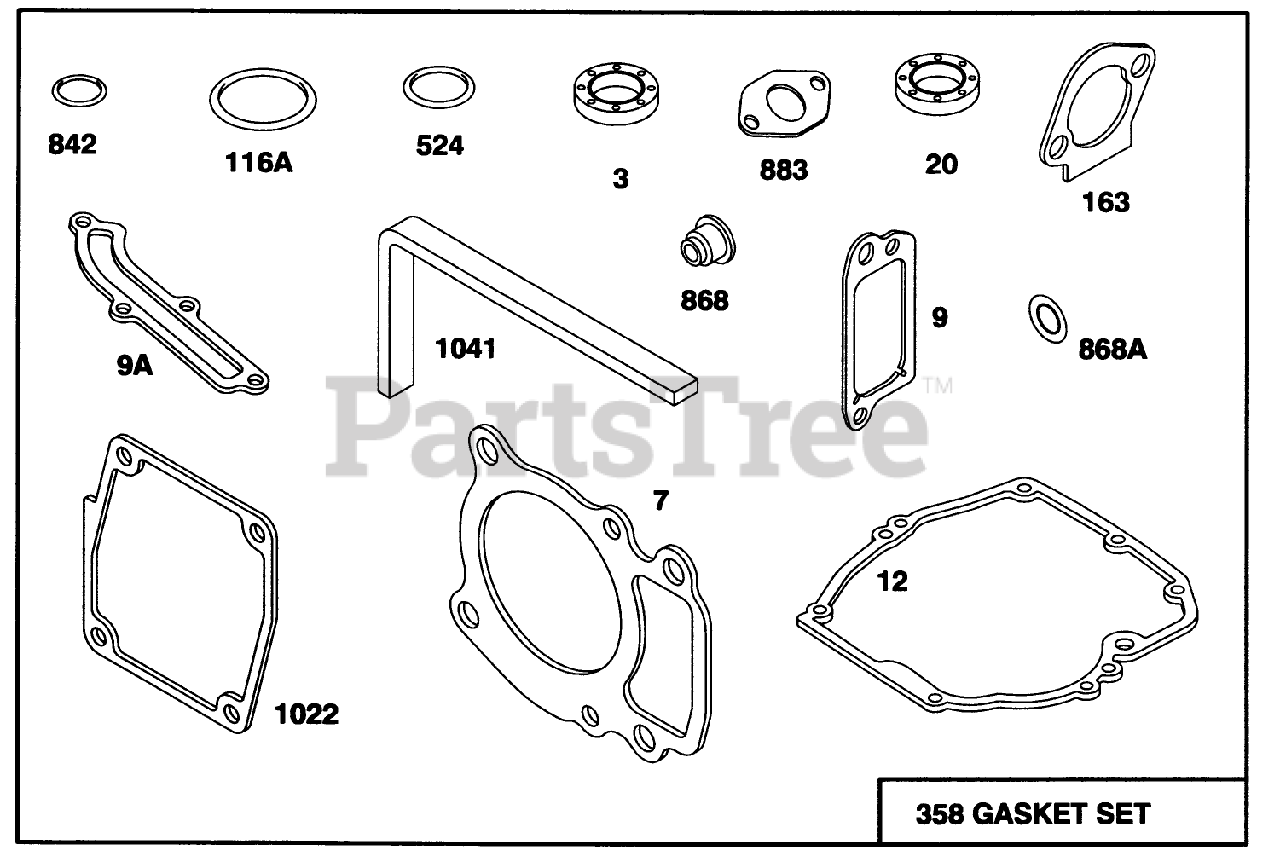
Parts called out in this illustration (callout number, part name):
104	FLOAT HINGE PIN
116	SEALING GASKET
118	VALVE KIT - NEEDLE
121	CARBURATOR OVERHAUL KIT
122	ADAPTER ASSEMBLY
134	Valve-Float (Includes Seat)
137	FLOAT BOWL GASKET
358	GASKET SET
634	SEAL WASHER
977	CARBURATOR GASKET SET
1039	FLOAT LIMITER
